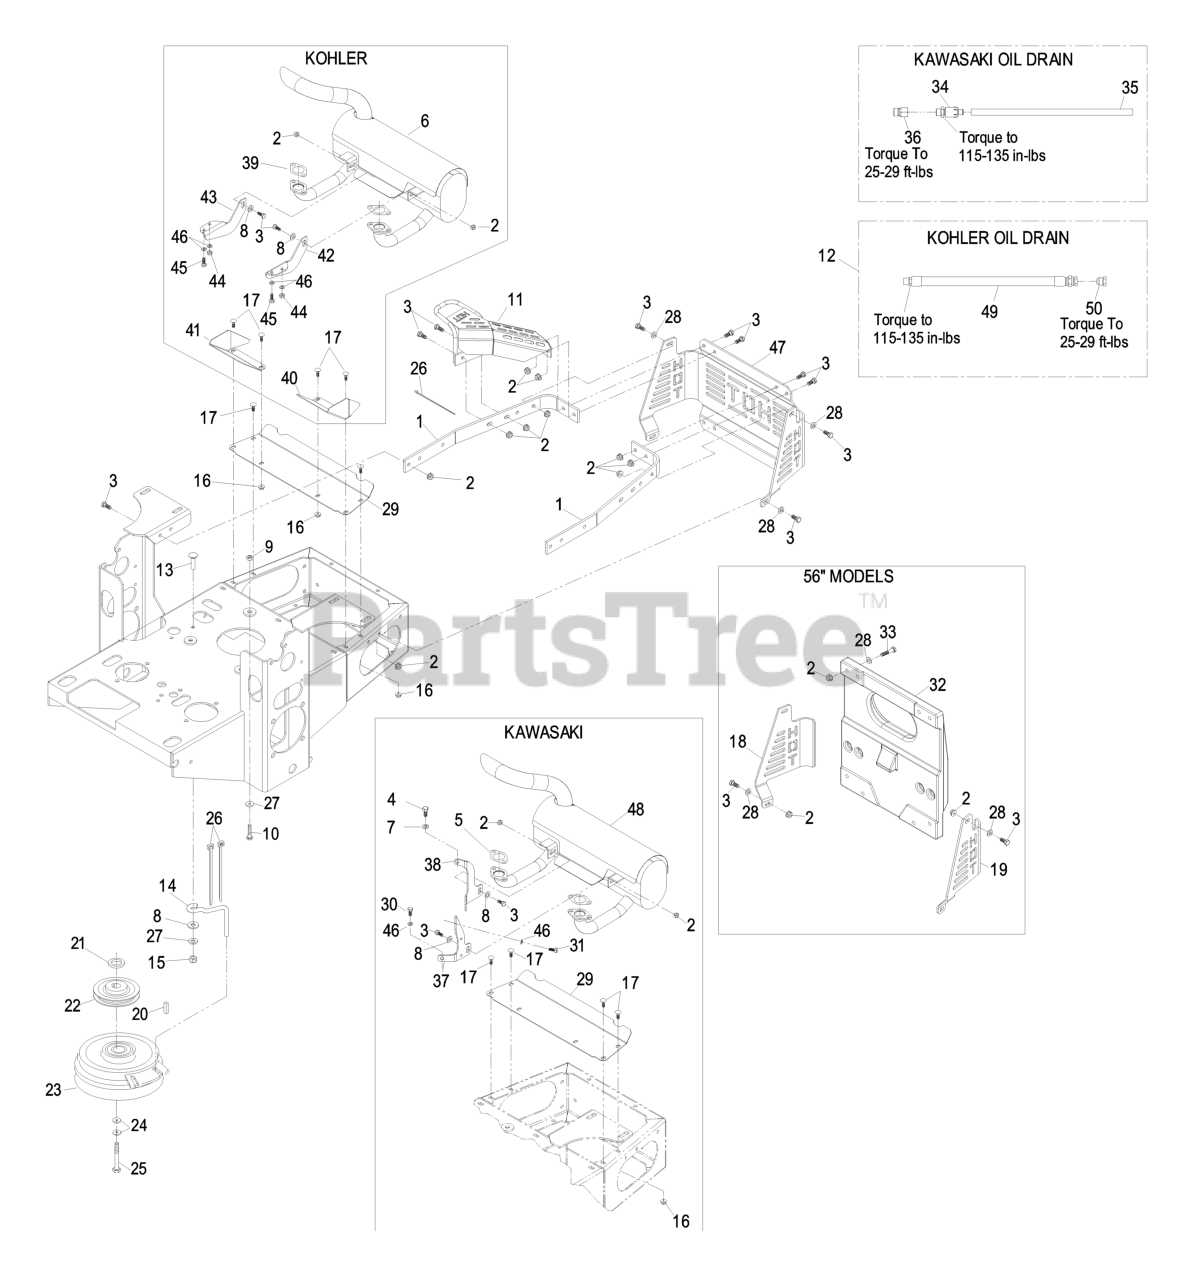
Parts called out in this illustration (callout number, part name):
1	STRAP-GUARD, RH
3	SCREW-HH
4	SCREW-HH
5	GASKET-EXHAUST
6	KIT,MUFFLER (18-23 KOH)
7	WASHER-LOCK
8	WASHER-FLAT
9	NUT-LOCK, NI
10	SCREW-HH
11	GUARD-TAILPIPE
13	Bolt-Carriage 5/16-18 X 1 1/4
15	NUT-LOCK, NI
16	NUT-HF
17	SCREW-CARR
18	GUARD-MUFFLER, RH
19	GUARD-MUFFLER, LH
21	SPACER-CRANKSHAFT
24	WASHER-SPRING
25	SCREW-HH
26	TIE-PLASTIC
27	WASHER-SPRING
28	WASHER-PLAIN
29	DEFLECTOR-SHORT
30	SCREW-HH
31	SCREW-HH
32	Counterweight, 60# (56")
33	SCREW-HH
34	VALVE-DRAIN, OIL
35	TUBE-DRAIN, OIL
36	ADAPTER
37	BRACKET-MUFFLER, LH
38	BRACKET-MUFFLER, RH
40	DEFLECTOR-AIR, LH,KC
41	DEFLECTOR-AIR, RH,KC
42	BRACKET-MUFFLER, LH
43	BRACKET-MUFFLER, RH
44	NUT-HEX
45	SCREW-HH
46	WASHER-LOCK
47	GUARD-REAR
48	MUFFLER KIT
50	PLUG
